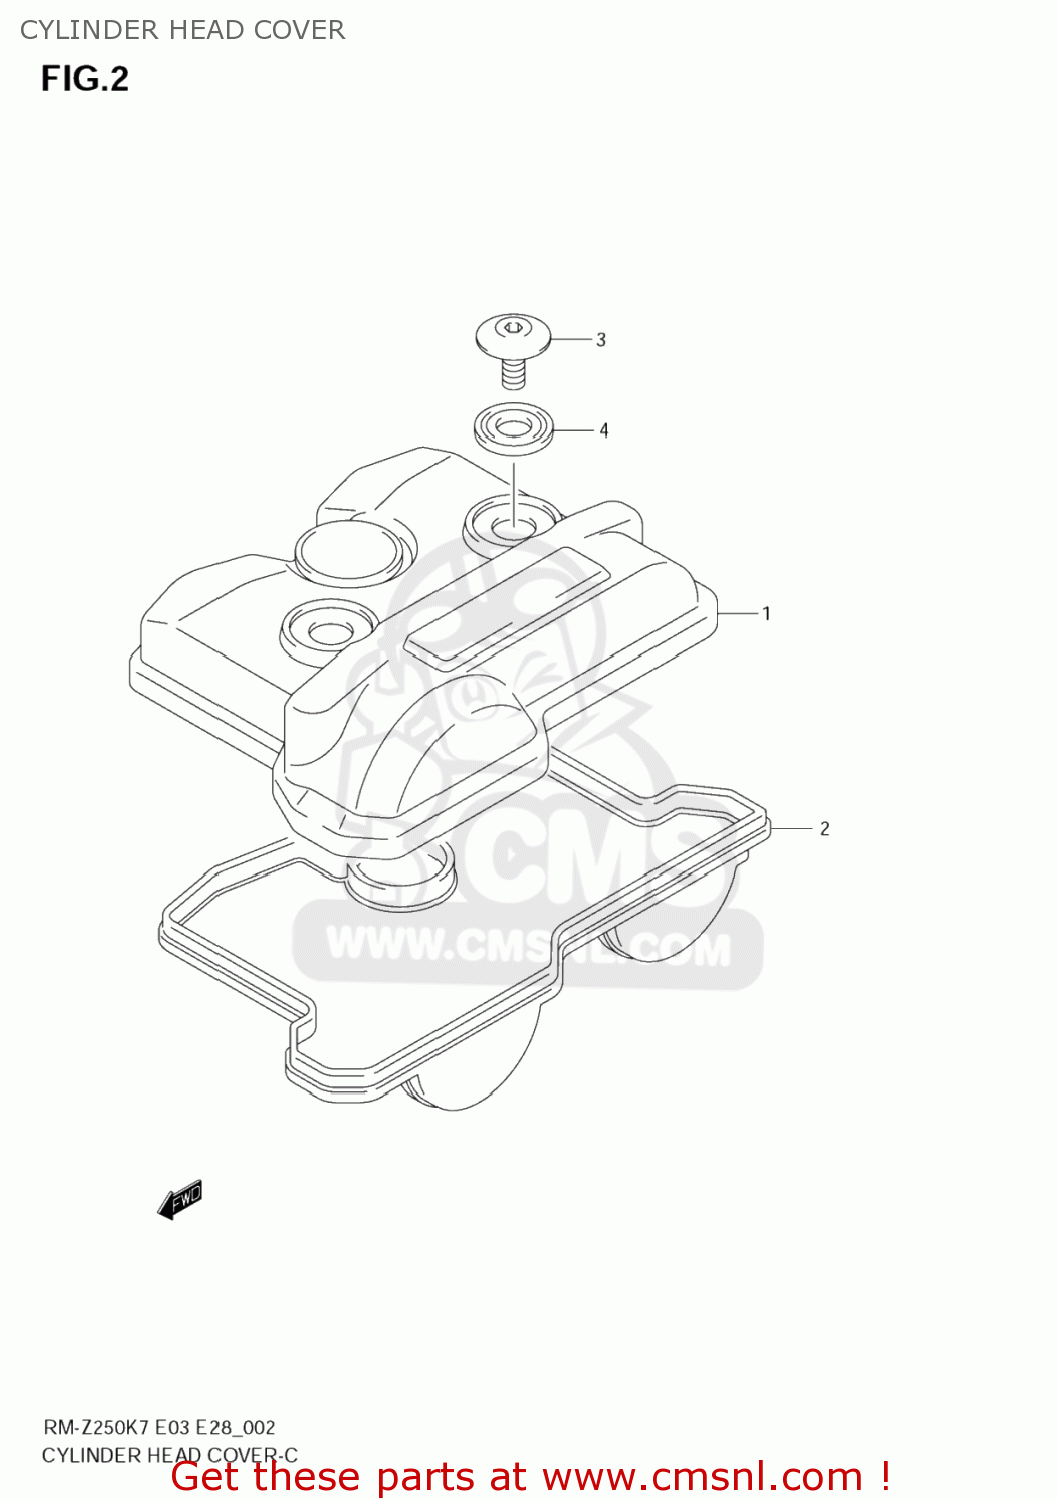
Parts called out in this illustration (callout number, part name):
1	COVER,CYLINDER HEAD
2	GASKET,CYL HEAD COVER (NAS)
3	BOLT(7X17.5)
4	WASHER,CYL HEAD COVER
